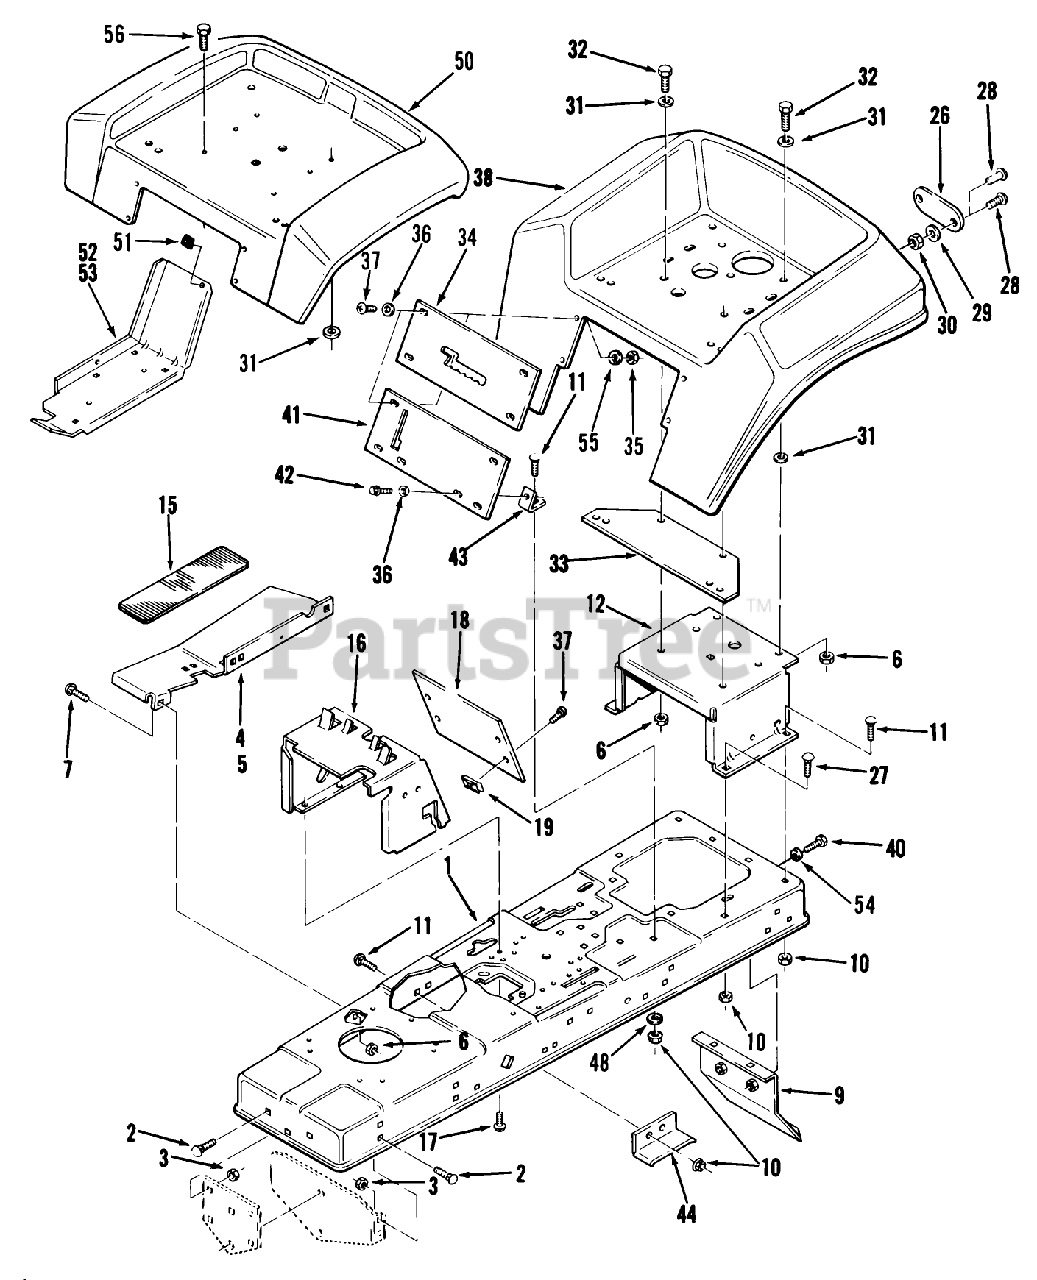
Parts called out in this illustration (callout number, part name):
2	CARRIAGE BOLT -4
7	CARRIAGE BOLT -4
11	CARRIAGE BOLT -4
12	SUPPORT-SEAT *R
15	PAD-FOOTREST
17	SCREW
29	WASHER
31	WASHER
42	Bolt
43	BRACKET-FENDER
50	FENDER *R
